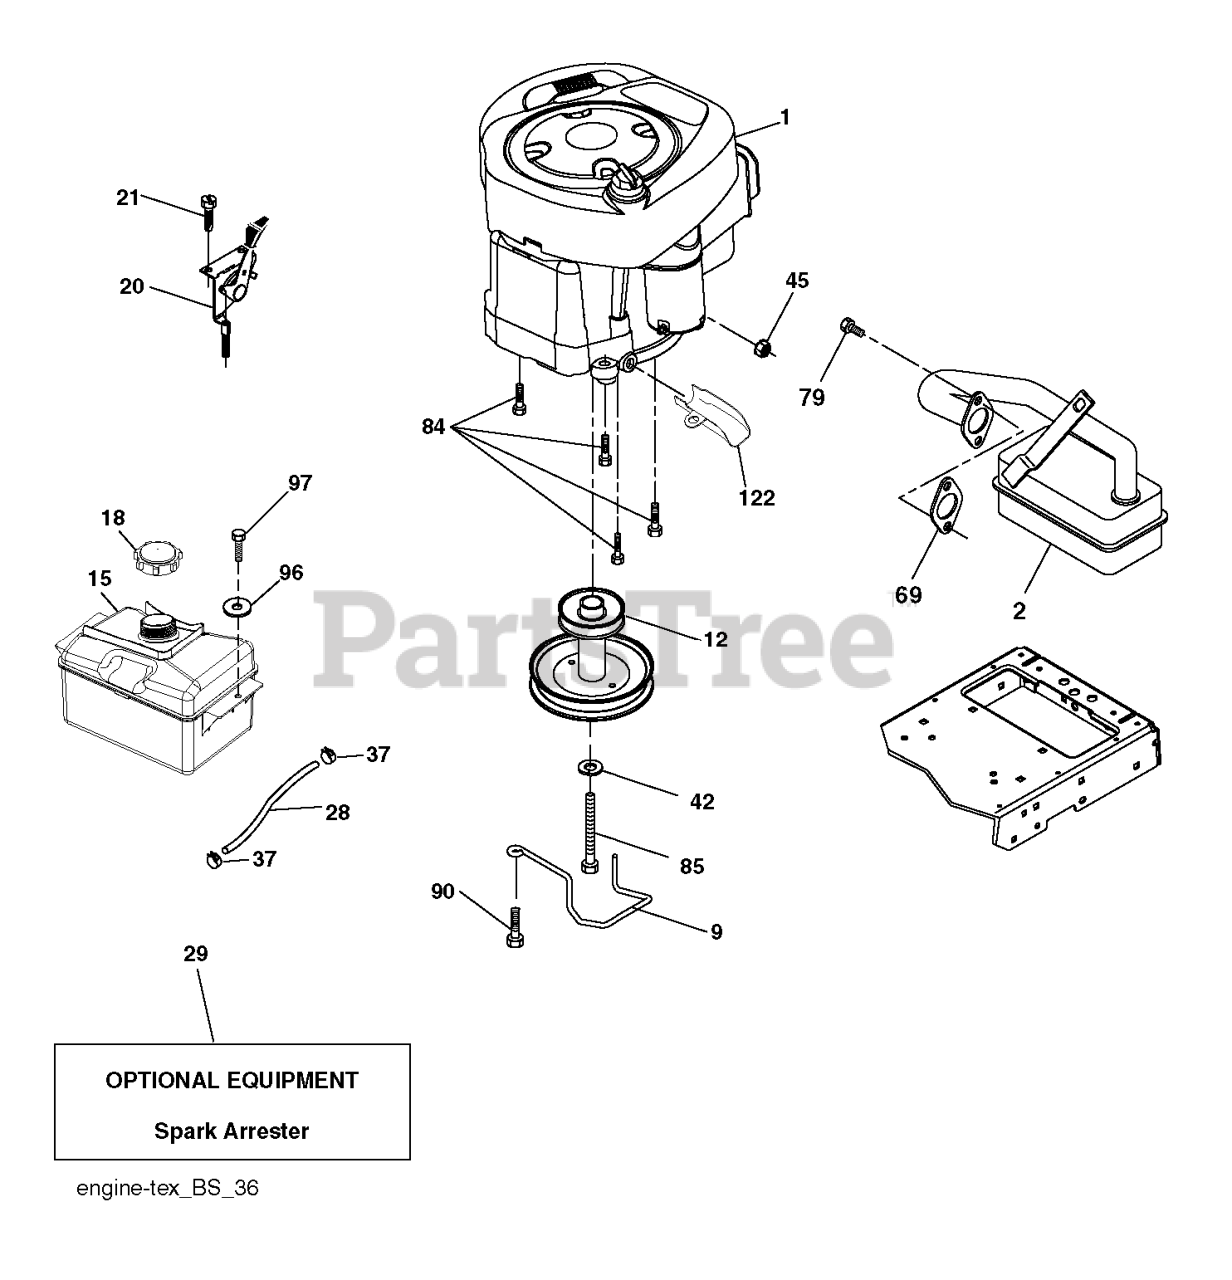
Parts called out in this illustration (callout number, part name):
2	MUFFLER.LT.BRIGGS.14HP.IC/OHV
9	KEEPER.BELT.ENGINE.4.2
12	PULLY ENGINE
15	RP TANK FUEL FRT 1.5 GAL
18	CAP ASM.FUEL.2.25"FR.
20	CONTROL.TH/CK.C.
21	SCREW.#10 X 0.750.BOS
28	LINE.FUEL.20"FRONT.EMI
29	KIT.SPARK ARRESTOR 794945 B&S
37	HOSE CLAMP
42	LOCKWASHER
45	NUT
69	REPL BY 532 27 22-93
79	SCREW.SOCKET HD.5/16-1
84	SCREW.3/8-16
85	BOLT HEX 7/16-20X4-1/4"
90	SCREW 3/8-16X1
97	SCREW HEXWSHR 1/4-20X3/4
122	EXTENSION DRAIN OIL
